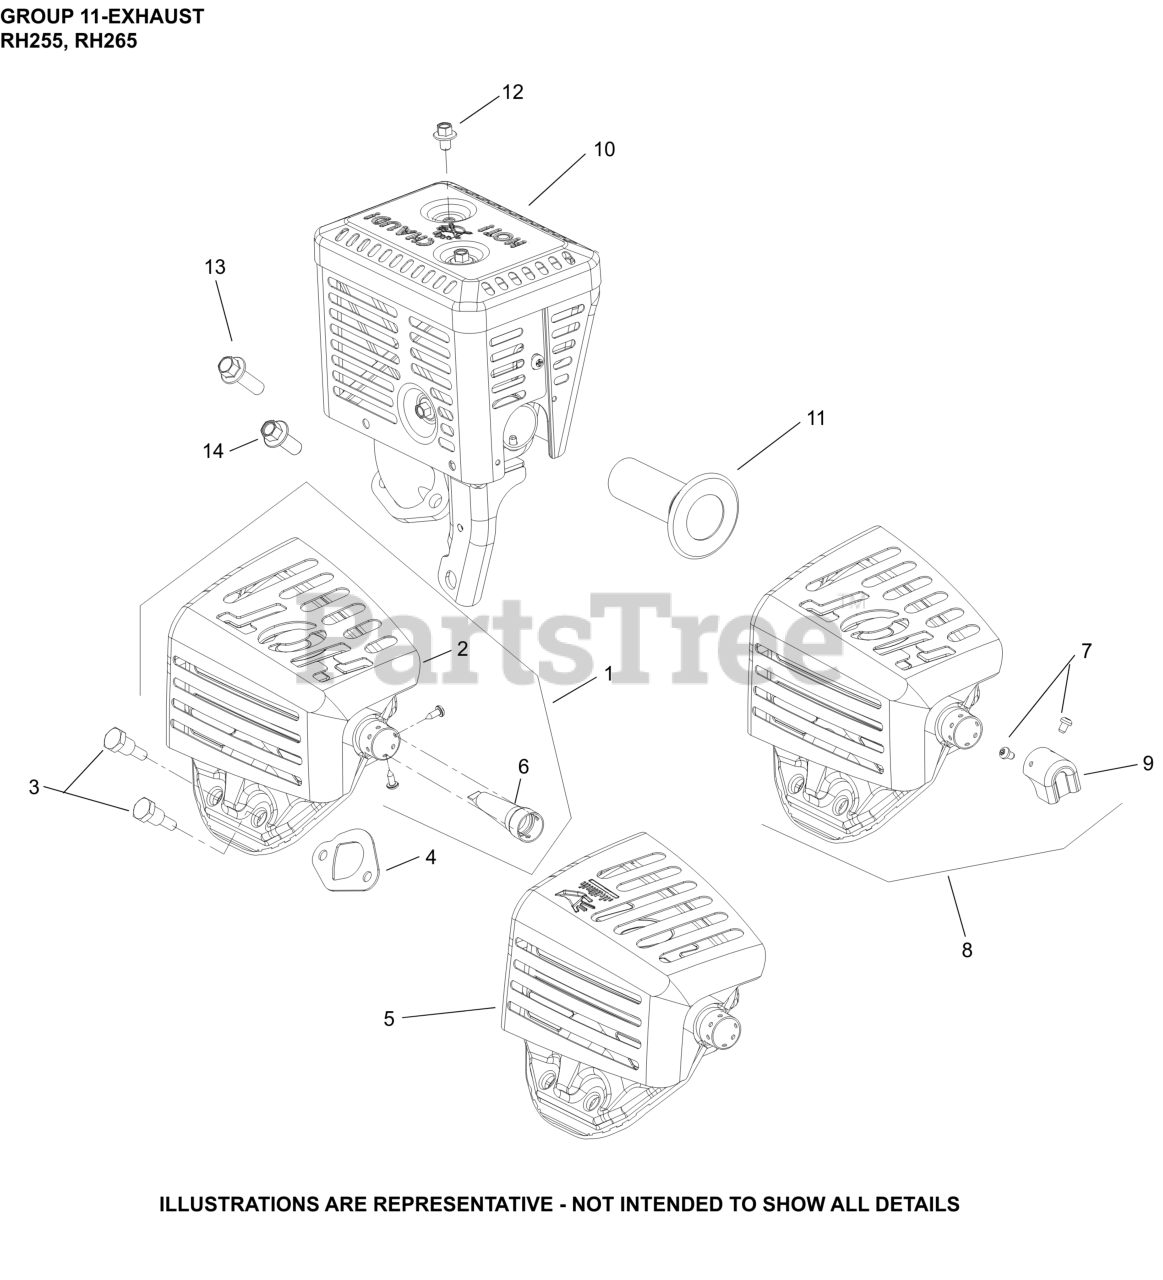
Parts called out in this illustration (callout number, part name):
2	MUFFLER ASSEMBLY
3	SCREW, SHOULDER
4	GASKET, MUFFLER
